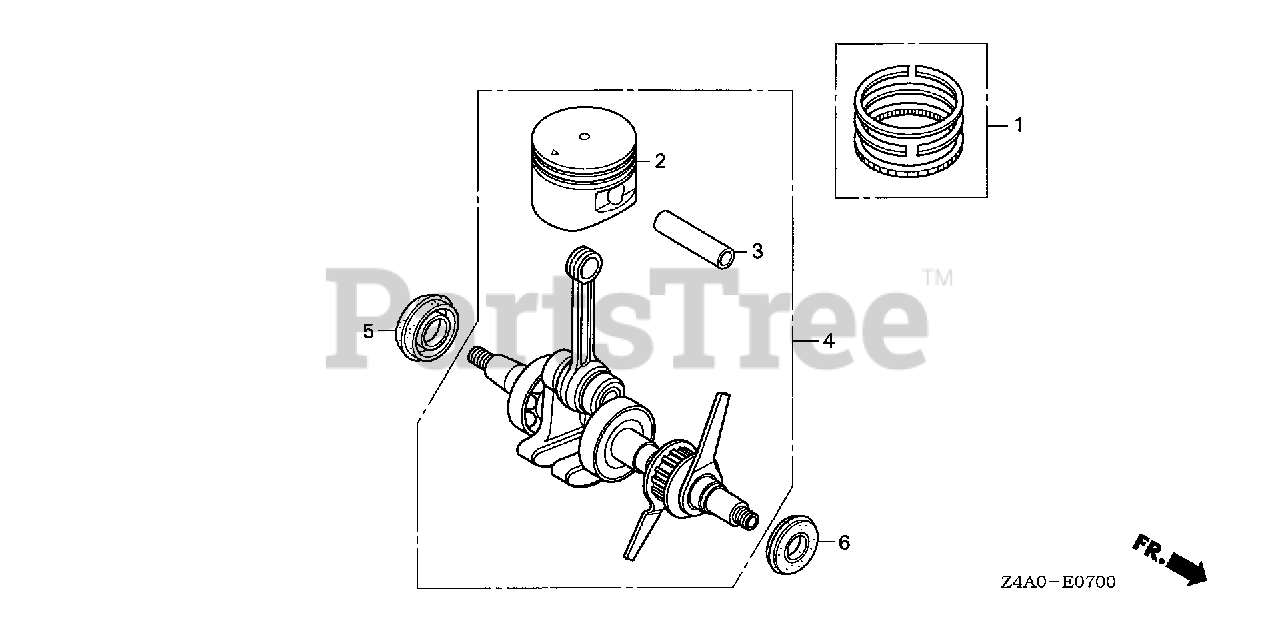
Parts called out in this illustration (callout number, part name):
1	RING SET, PISTON
2	PISTON
2	PISTON (STD)
3	PIN, PISTON
4	CRANKSHAFT
5	OIL SEAL (12X24X5)
6	OIL SEAL (10X20X5)
